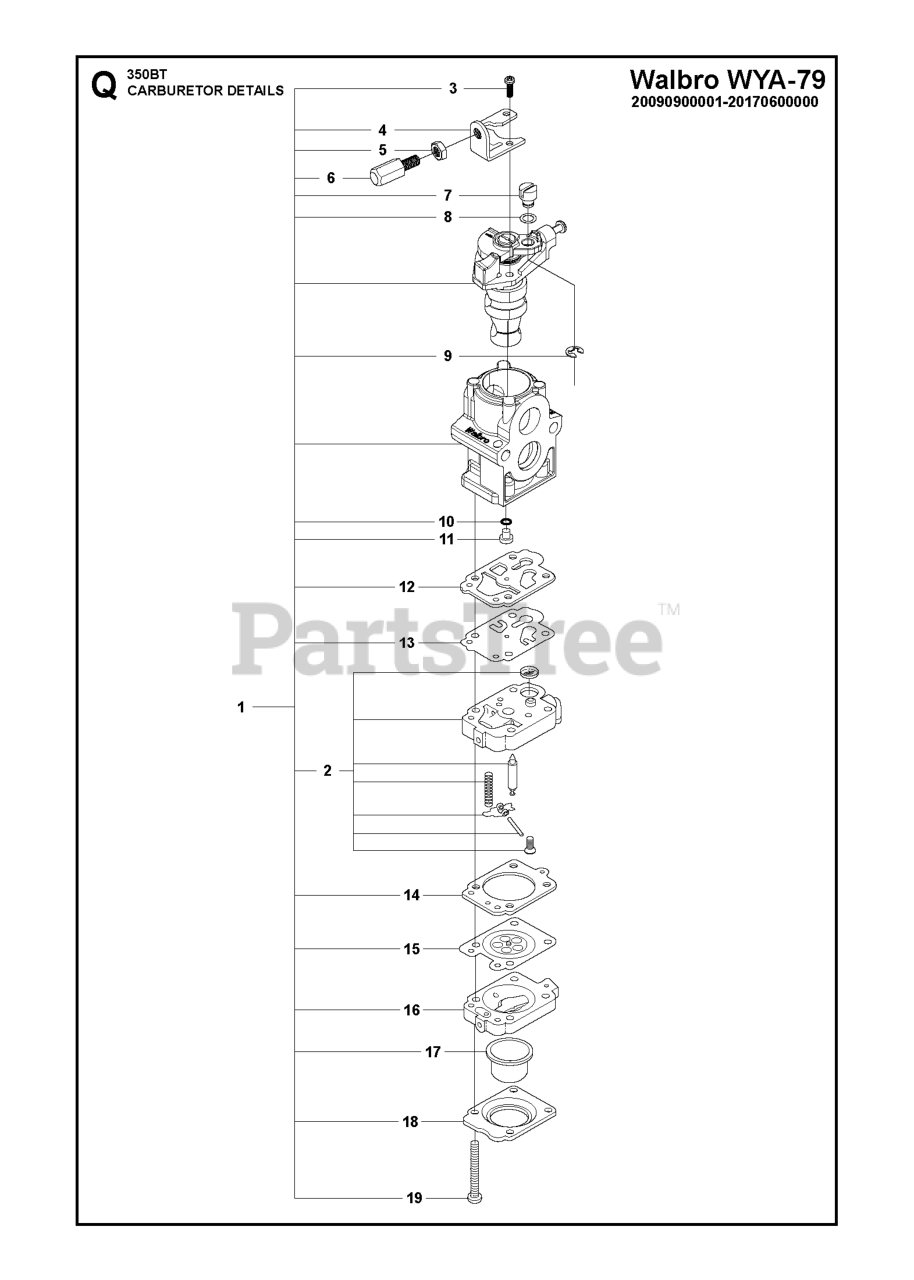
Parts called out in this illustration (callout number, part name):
1	CARBURETOR
2	BODY-A-PUMP
5	NUT
6	ADJUSTER
11	JET (RPLS T104881250)
